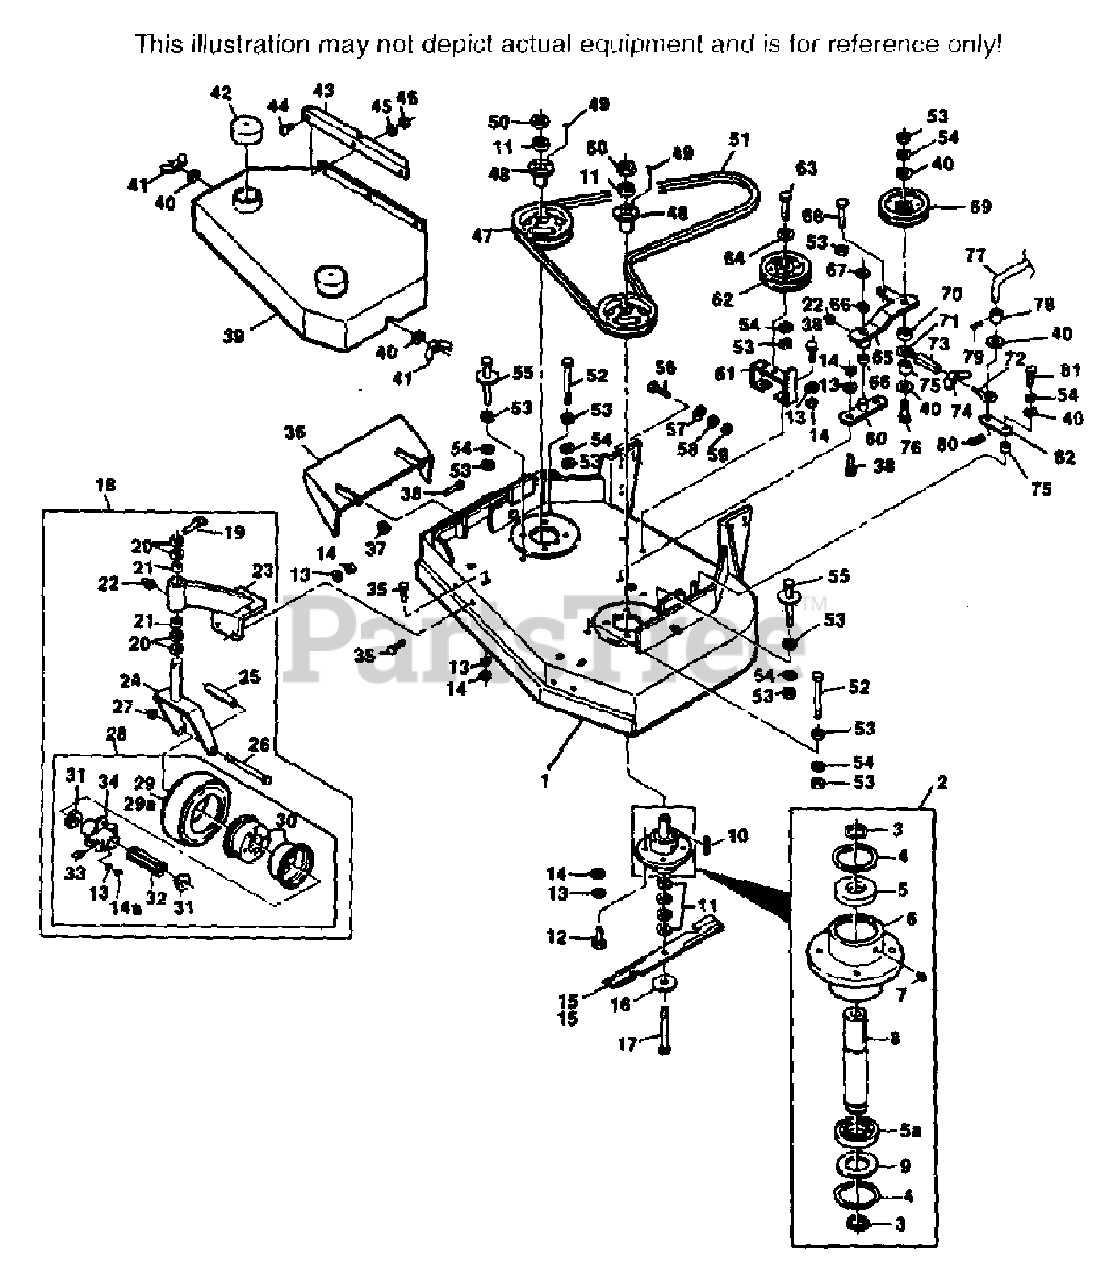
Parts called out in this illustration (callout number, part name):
1	CUTTER DECK WLD.(INCL. DECALS)
2	CUTTER SPINDLE ASSY.(INCL 3-9)
3	RETAINING RING, 1" EXT.-INVERTED
4	RETAINING RING, 2-7/16 INT-BASIC
5	BEARING, CUTTER SPINDLE
6	SPINDLE HOUSING
7	GREASE FITTING, STR. 5/16 SERR.
8	SPINDLE, CUTTER BLADE
9	WASHER, 1-15/16 X 2-13/32 X 16 GA.
10	KEY, 1/4 X 1/4 X 2
11	SPACER, CUTTER BLADE
15	CUTTER BLADE, 20" STD.
16	FLAT WASHER, 5/8W
17	HEX HEAD BOLT, 5/8-11 X 9-1/2
18	CASTER ASSY.(INCL. 19-28)
19	QUICK PIN
20	SPACER, CASTER YOKE, 1/2 LONG
21	BRONZE BEARING
22	GREASE FITTING, STR. 1/4-28
23	SUPPORT ASSY.(INCL. 21-22)
24	CASTER YOKE WLD.
25	SLEEVE, CASTER WHEEL BEARING
26	HEX HEAD BOLT, 1/2-13 X 5-1/2
28	WHEEL ASSY.(INCL. 13-14, 29-34)
29	TIRE ONLY, CASTER WHEEL
29A	INNER TUBE ONLY, CASTER WHEEL
30	RIM PAIR, CASTER WHEEL
31	RETAINER, BEARING, CASTER WHEEL
32	ROLLER BEARING, CASTER WHEEL
33	GREASE FITTING, 45' 1/4-28
34	HUB ASSY. W/BOLTS, CASTER WHEEL
36	DISCHARGE CHUTE WLD.
37	HEX NUT, 5/16-18 ELASTIC STOP
39	BELT COVER ASSY.(INCL. DECALS)
40	WASHER, 25/64 X 15/16 X 12 GA.
41	WING NUT, 3/8-16
42	SPINDLE SHIELD
43	BELT COVER SKIRT
47	PULLEY(INCL. 48-49)
48	TAPER HUB
51	BELT, BLADE DRIVE
55	BELT GUIDE WLD.
57	WASHER, 15/32 X 59/64 X 16 GA.
59	HEX NUT, 7/16-14 ELASTIC STOP
60	IDLER PIVOT WLD.
61	IDLER PULLEY SUPPORT
62	PULLEY, BELT GUIDE
64	WASHER, 13/32 X 13/16 X 16 GA.
65	IDLER ARM ASSY.(INCL. 22 & 66)
66	BRONZE BEARING
67	RETAINING RING, 3/4 EXT.-"E"
69	IDLER PULLEY, BELT CLUTCH - STD.
69	IDLER PULLEY, BELT CLUTCH - WIDE
70	SPACER, IDLER
71	EYEBOLT, LH
72	EYEBOLT, RH
73	TURNBUCKLE
74	WING NUT, 5/16-18
75	SLEEVE, CAM CLUTCH
77	BLADE CLUTCH ROD
78	SLEEVE, CLUTCH ROD
80	HAIR PIN, LARGE
82	CAM LINK WLD.
